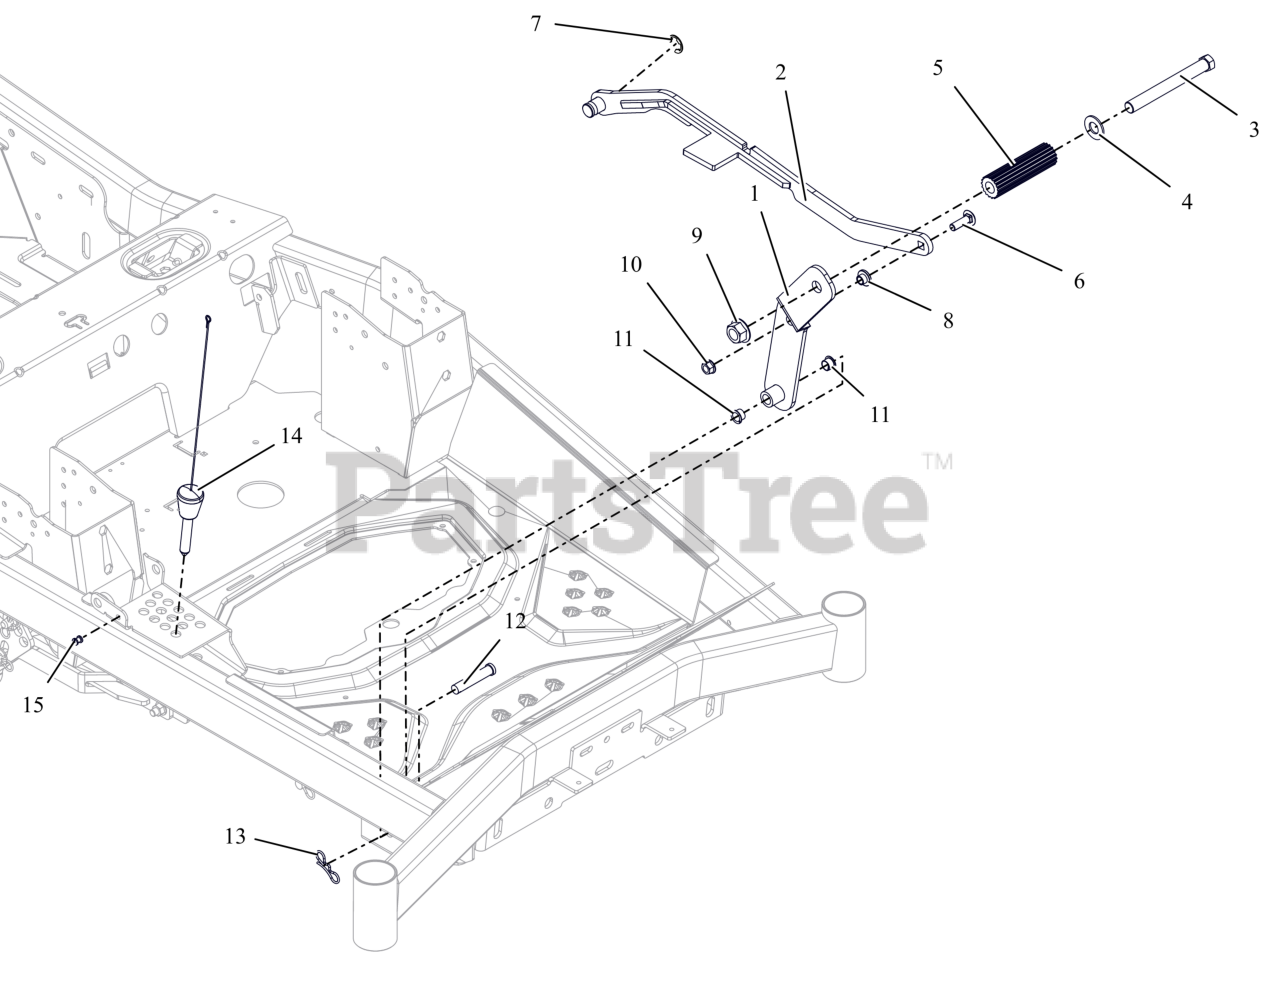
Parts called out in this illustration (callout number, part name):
1	WLDMT- FOOT PEDAL
2	LINK- DECK LIFT
3	BLT, HEX .62-11X5.50 G5 FBP
4	WSHRFLT 5/8SAE CARBHARD FBP
5	ROD, FOOT PEDAL (BLACK)
6	BLT,RHSSN .38-16X1.25 G5 ZCC
7	RING, RETAINING-E .750X.050
8	BSHG-FLG .385X.500X.875X.406
9	NUT,FLG-TOP LK .625-11 FBP
10	NUT-LK-CTR-FLG .375-16 GF ZCC
11	BUSHING, POLYLINER-.50 SPLIT
12	PIN-CLEV .494X2.50 BRIGHT ZINC
13	PIN, BOWTIE .091X1.875 ZCC
14	PIN- MAGNETIC .50X2.70
15	POST, & SCREW, PUSH LOCK .25 X .25
